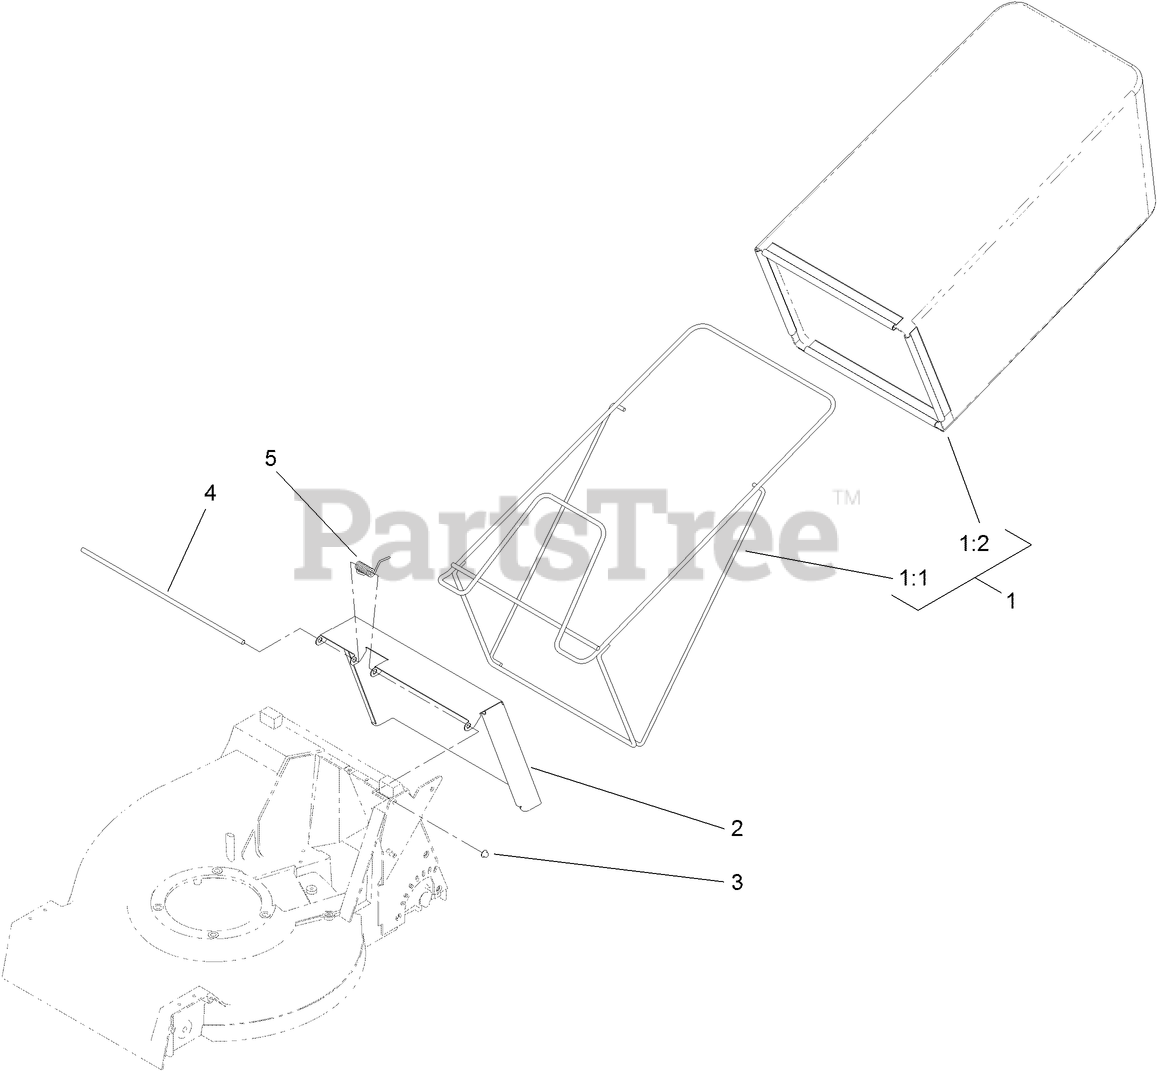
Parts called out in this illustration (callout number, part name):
1	GRASS BAG ASM
1:1	FRAME ASM
1:2	BAG-GRASS
2	DOOR-DISCHARGE, REAR
3	PUSHNUT-CAP, WASHER
4	ROD-DOOR
5	SPRING-TORSION, DOOR
